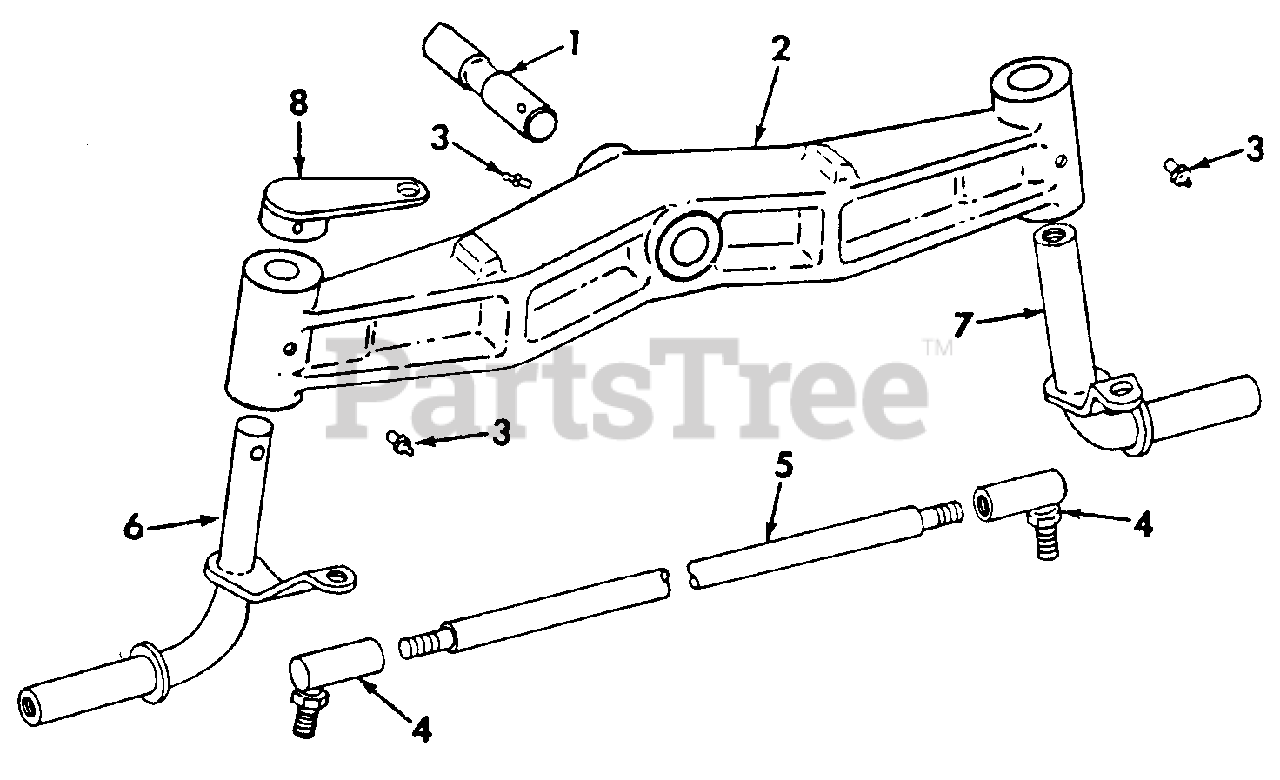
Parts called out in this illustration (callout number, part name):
1	Pin, Front Axle Pivot
2	Axle, Front
3	Fitting, 3/16 Drive Type Str Lube
4	Joint, Tie Rod
8	Arm Assy, Drag Link
